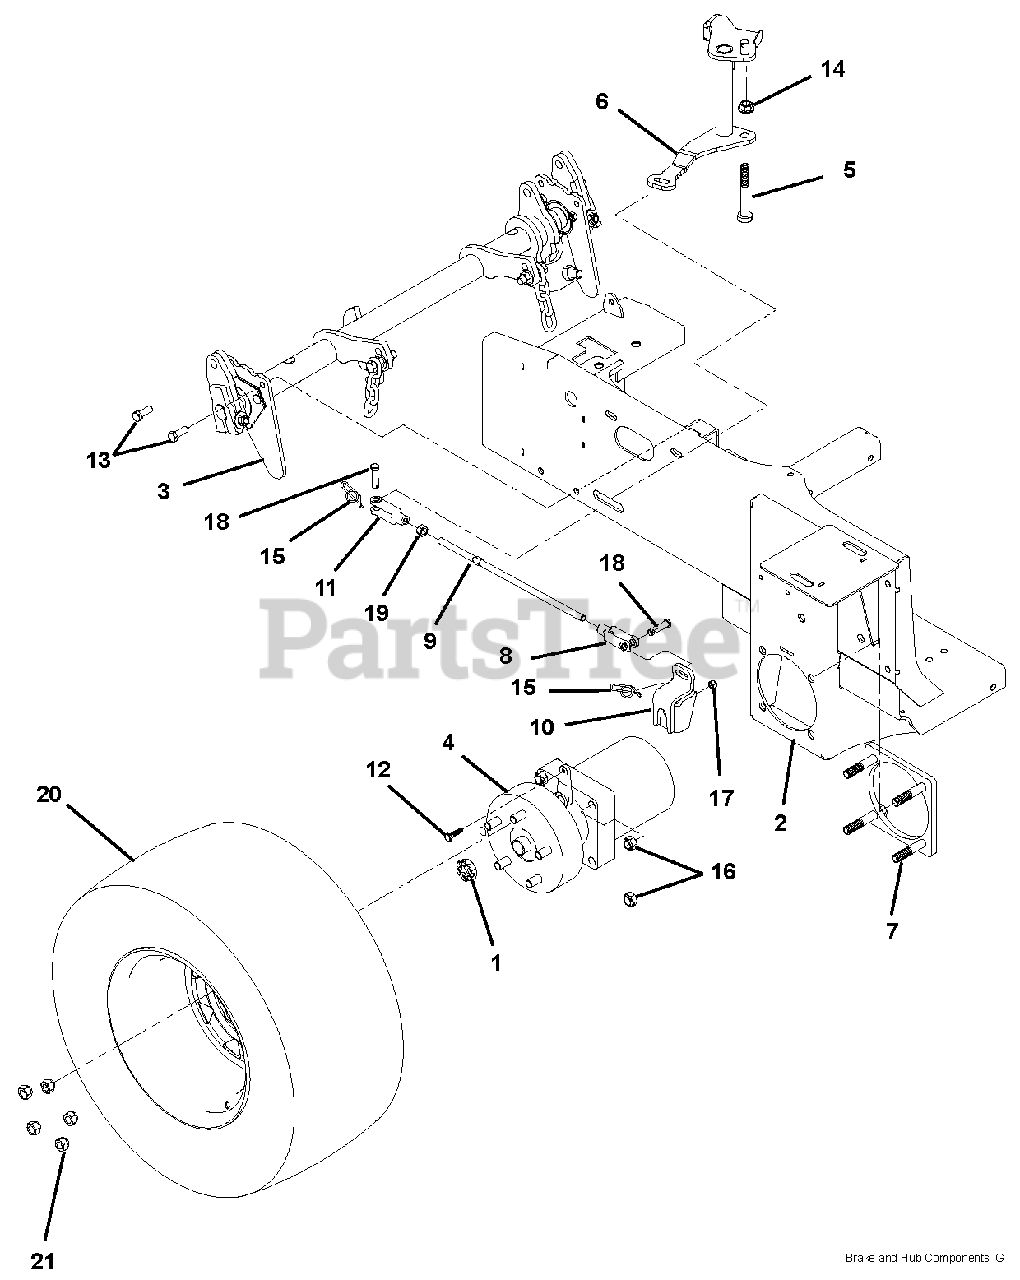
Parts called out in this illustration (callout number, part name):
1	Nut, Hub Retaining Hydro-Gear Wheel Motor
2	Unibody Weldment w/Decals
3	Rear Lift Rod Assembly (See "Lift Rod" on page 14.)
4	Motor, LH Wheel
5	Bearing Shield 1/2"
6	Park Brake Control Arm LH
7	Weldment, Wheel Motor Plate
8	Yoke, 3/8-24 LH Adjustable
9	Rod, Straight Park Brake Control
10	Weldment, Brake Arm EXT - Parker-Gear Wheel Motor
11	Yoke, 3/8-24 RH Adjustable
12	Bolt, 1/4-20 x 1.00 Hex 5
13	Bolt, 3/8-16 x 1.00 Hex 5
14	Bolt, 1/2-13 x 2.75
15	Ring, Rue .375 x .054 x 1.254
16	Nut, 1/2-13 STD HEX
17	Nut, Locking, Nylon .250-20
18	Pin, CVS .375 x 1.38 x 1.14
19	Nut, Hex .375-24
20	Assembly, Tire & Rim - 24 x 11.50-12
21	Nut, 1/2-20 Lug
